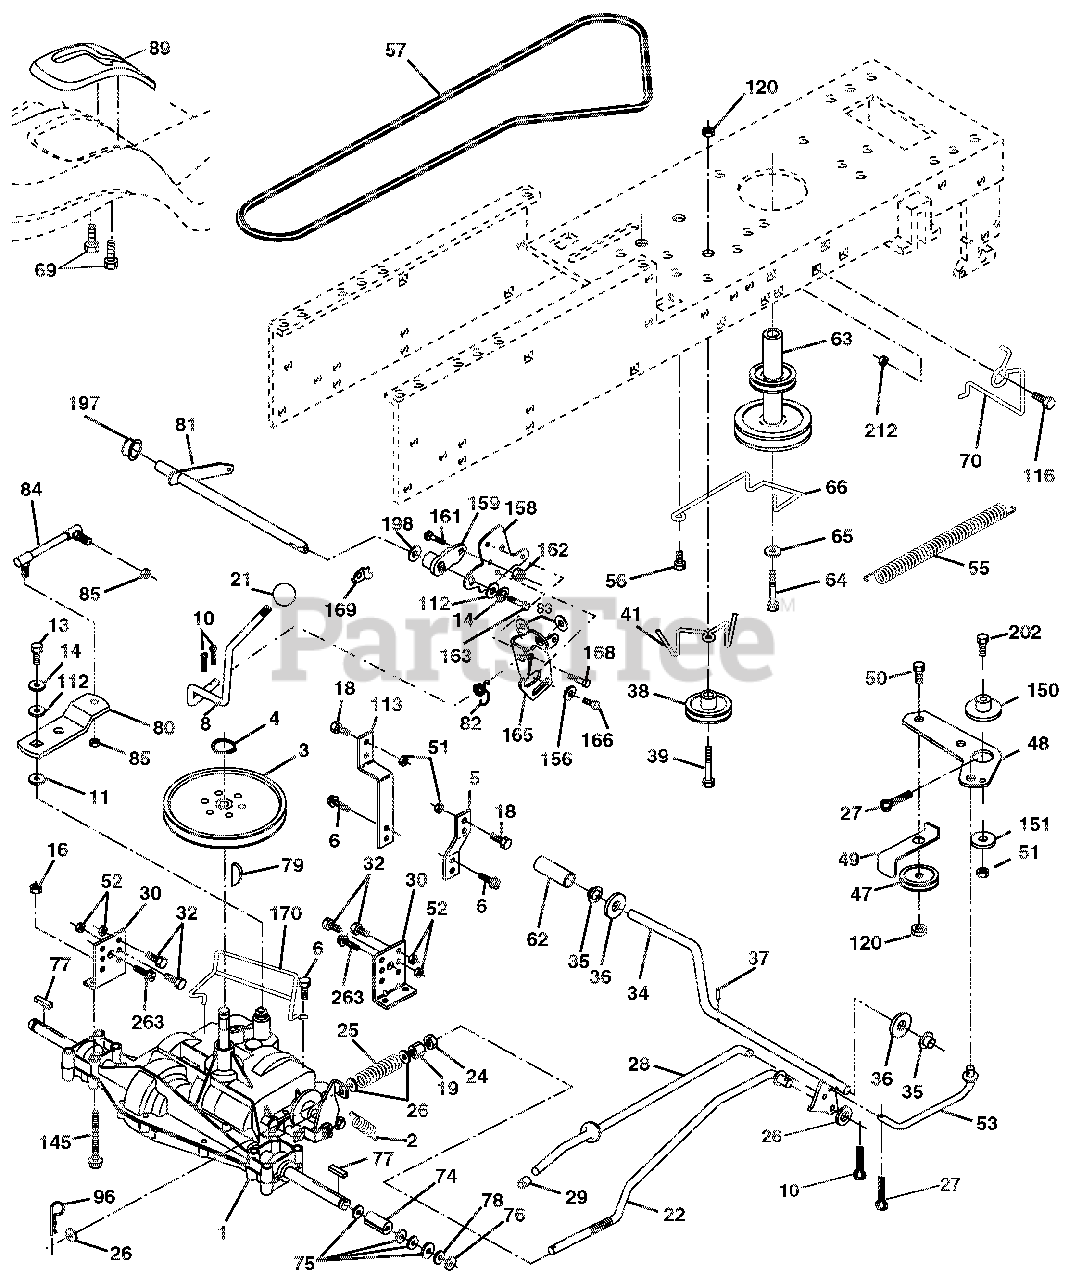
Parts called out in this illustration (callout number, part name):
1	TRANSAXLE PEERLESS 206-545C (165670) (ORDER PARTS FROM TRANSAXLE MANUFACTURER.)
2	Spring Return Brake T/a Zinc
3	PULLEY.TRANSAXLE.18/20"TIRES
4	Ring, Retainer
5	Strap Torque 30 Degrees
6	SCREW.5/16-18X3/4.SMGML.TAP/R
8	Rod Shift Fender Adjust Lt
10	Pin Cotter 1/8 x 1 Cad
11	WASHER.PLATE.SHF..388 SQ.HOLE
13	BOLT.1/4-28 UNF.GR8.W/PATCH
14	Washer, Lock 1/4
16	Locknut, Washer Insert 5/16-18
18	Bolt, Fin Hex 3/8-16 unc x 1
19	Locknut, Washer Insert 3/8-16
22	Rod Brake Blk Zinc 26 840
24	Nut, Hex, Jam 3/8-16
25	Spring Rod Brake 2 00 Zinc
26	WASHER.13/32 X 13/16 X 16 GA.
27	PIN.COTTER.1/8 X 3/4.CAD.
28	Rod Brake Parking LT/YT
29	Cap Brake Parking
30	BRACKET
32	Bolt, Hex Head 5/16-18 x 3/4
34	Shaft Asm Pedal Foot
35	BEARING.NYLON.BLK..629 ID.
36	Washer 21/32 x 1 x 16 Ga.
37	PIN.ROLL.3/16X1
38	Pulley Composite Flat
39	BOLT.RDHD.3/8-16UNC X2-3/4 GR5
41	Keeper Belt Flat Idler
47	Pulley Idler V Groove
48	Bellcrank Asm
49	Retainer Belt Style Spring
50	BOLT.CARR.SH.3/8-16X1-1/2.GR5
51	Nut, Hex, Crownlock 3/8-16
52	Nut, Hex, Crownlock 5/16-18
53	Link Clutch
55	SPRING.RETURN.CLUTCH.6.75
56	Screw 3/8-16 x <
57	V-Belt Ground Drive
62	COVER PEDAL BLK ROUND
63	Engine Pulley
64	BOLT.HEX.7/16-20X4XGR5-1.5THR.
65	WASHER.LOCK.HVY HLCL.SPR.7/16
66	Keeper Belt Engine Foolproof
69	SCREW.HEX.WSH.HI-LO.1/4X1/2UNC
70	Guide Belt Mower Drive RH
74	SPACER.AXLE.HYDRO/PEERLES
75	WASHER.25/32 X 1 1/4 X 16 GA.
76	E-RING.#5133-75
77	KEY.SQUARE.2.0 X .1845/.1865
78	WASHER.25/32 X 1-5/8 X 16GA.
79	KEY.WOODRUFF
80	ARM.SHIFT
82	Spring Torsion T/a
83	Washer 17/32 x 3/4 x 16 Ga.
85	NUT.LOCK.CENTER.1/4-28 FNTHD.
89	CONSOLE.SHIFT
96	RETAINER SPRING
112	WASHER.9/32 X 3/4 X 10 GA.
113	Strap Torque LT
116	Bolt, Carriage 3/8-16 x 1
120	Nut, Hex, Flangelock 3/8-16
145	BOLT 5/16-18 X 2 1/2 G.5
150	Spacer Retainer
151	WASHER.13/32 X 2 X 10 GA.
156	Washer Srrted 5/16ID x 1.125
158	BRACKET
159	HUB.SHIFT
161	Bolt Rdhd Sqnk 1/4-20 x 3/4
162	Nut Crownlock 1/4-20 unc
163	Bolt Hex Fin 1/4-20 unc x 1 Gr
165	BRACKET
166	Screw 5/16-18 x 5/8
168	Bolt Shoulder 5/16-18 x .561
169	Plate Fastening
170	Keeper Belt Transaxle Gear
197	Nyliner Snap-In
198	Washer Nyliner
202	BOLT.RDHD.3/8-16UNCX1-3/4.GR5
212	Nut, Hex, Flangelock 3/8-16
263	SCREW.HEXWSH THDR3/8-16X3/4.BL
